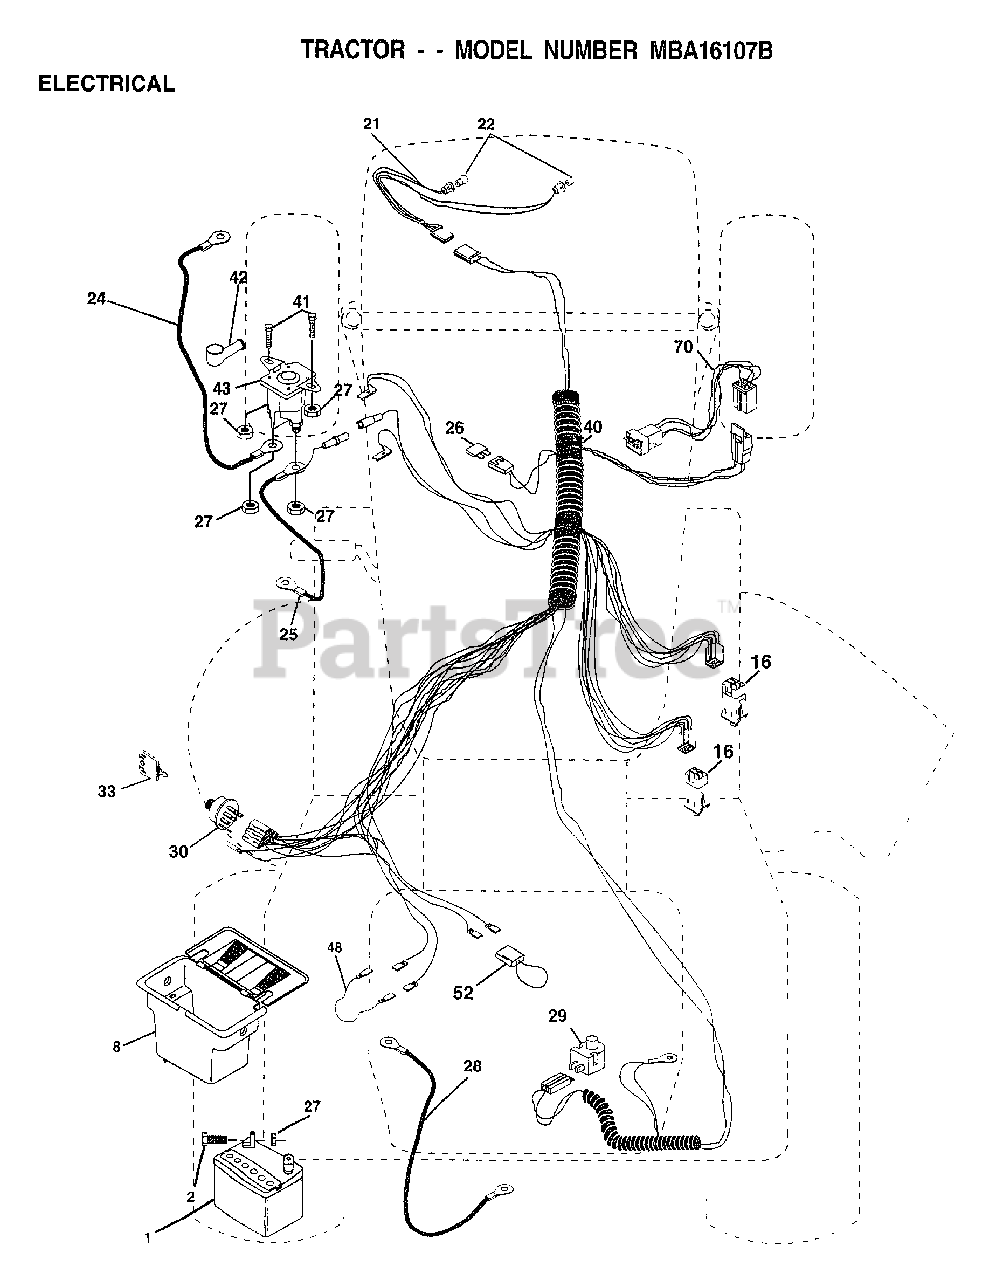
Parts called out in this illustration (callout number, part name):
2	BOLT LT
8	"CASE,BATTERY.MECH"
16	SWITCH INTERLOCK
21	HARNESS.ASM.LIGHT W/4152J
22	HEADLAMP BULB
24	CABLE ASM.
25	CABLE.BTRY.6GA.RD
26	FUSE.15 AMP
27	NUT
28	CABLE T
29	SWITCH SEAT
30	SWITCH.IGN.
33	KEY MLD GEN DELTA
40	HARNESS IGN
41	BOLT HXHD FIN
48	ADAPTER AMMETER
52	PROTECTION LOOP
70	HARNESS ENGINE
